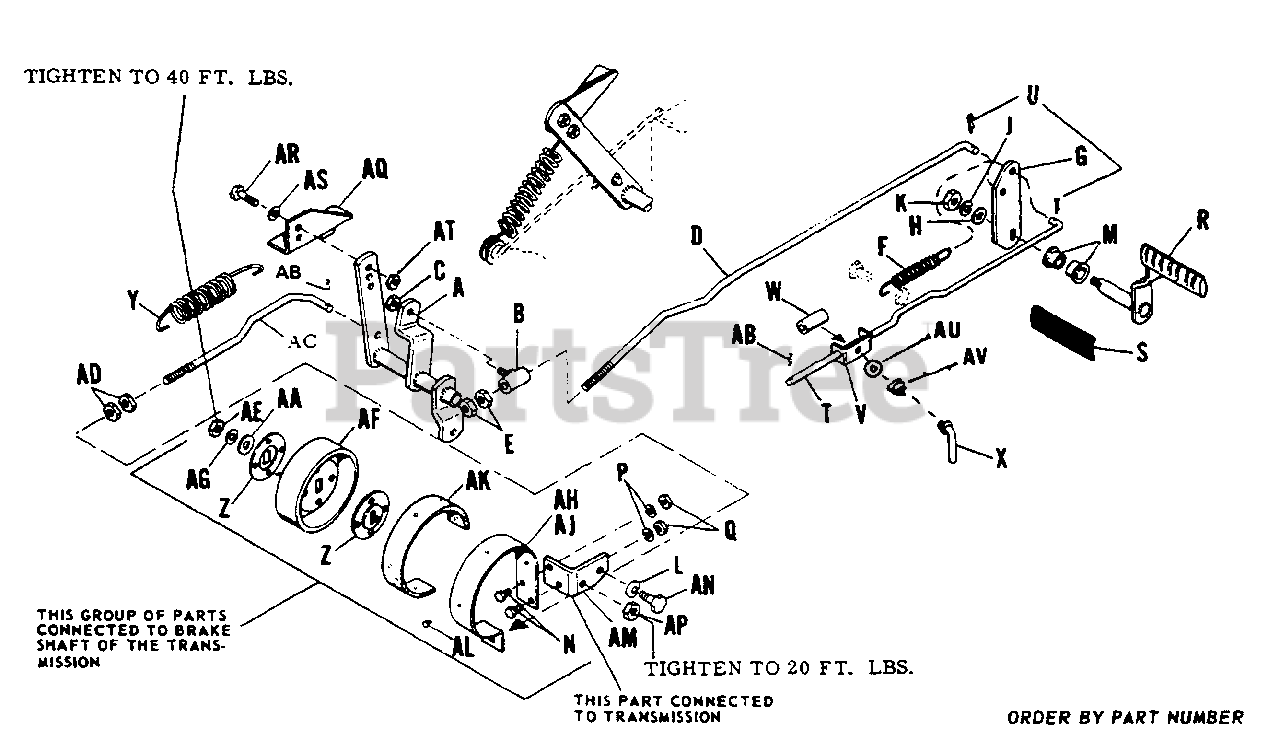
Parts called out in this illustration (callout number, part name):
A	Pivot Lever Assembly
B	Rod Guide Assembly
C	Hex Lock Nut, 5/16"-18
D	Brake and Clutch Rod
E	Hex Nut, 5/16"-18
F	Tension Spring
G	Foot Pedal Arm
H	Washer, Plain, 3/8"
J	Lock Washer, 3/8"
K	Hex Nut, 3/8"-16
L	Lock Washer, 3/8"
N	Hex Capscrew, 1/4"-20 x 3/4" lg.
P	Lock Washer, 1/4"
Q	Hex Nut, 1/4"-20
R	Foot Pedal Assembly
S	Pedal Pad
T	Parking Brake Rod
U	Cotter Pin, 1/8" x 3/4" lg.
V	Parking Brake Bracket Assy.
X	Parking Brake Lock
Y	Tension Spring
Z	Special Washer
AA	Washer, Plain, 3/8"
AB	Cotter Pin, 3/32" x 3/4" lg.
AC	Brake Rod
AD	Hex Nut, 3/8"-16
AE	Hex Nut, 7/16"
AF	Brake Drum
AG	Lock Washer, 7/16"
AH	Brake Band Assembly
AK	Brake Lining
AM	Brake Band Bracket
AN	Hex Capscrew, 3/8"-16 x 1" lg.
AP	Hex Nut, 3/8"-16
AQ	Spring Bracket
AR	Hex Capscrew 5/16"-18 x 3/4" lg.
AS	Lock Washer, 5/16"
AT	Hex Nut, 5/16"-18
AU	Plain Washer, 7/16"
